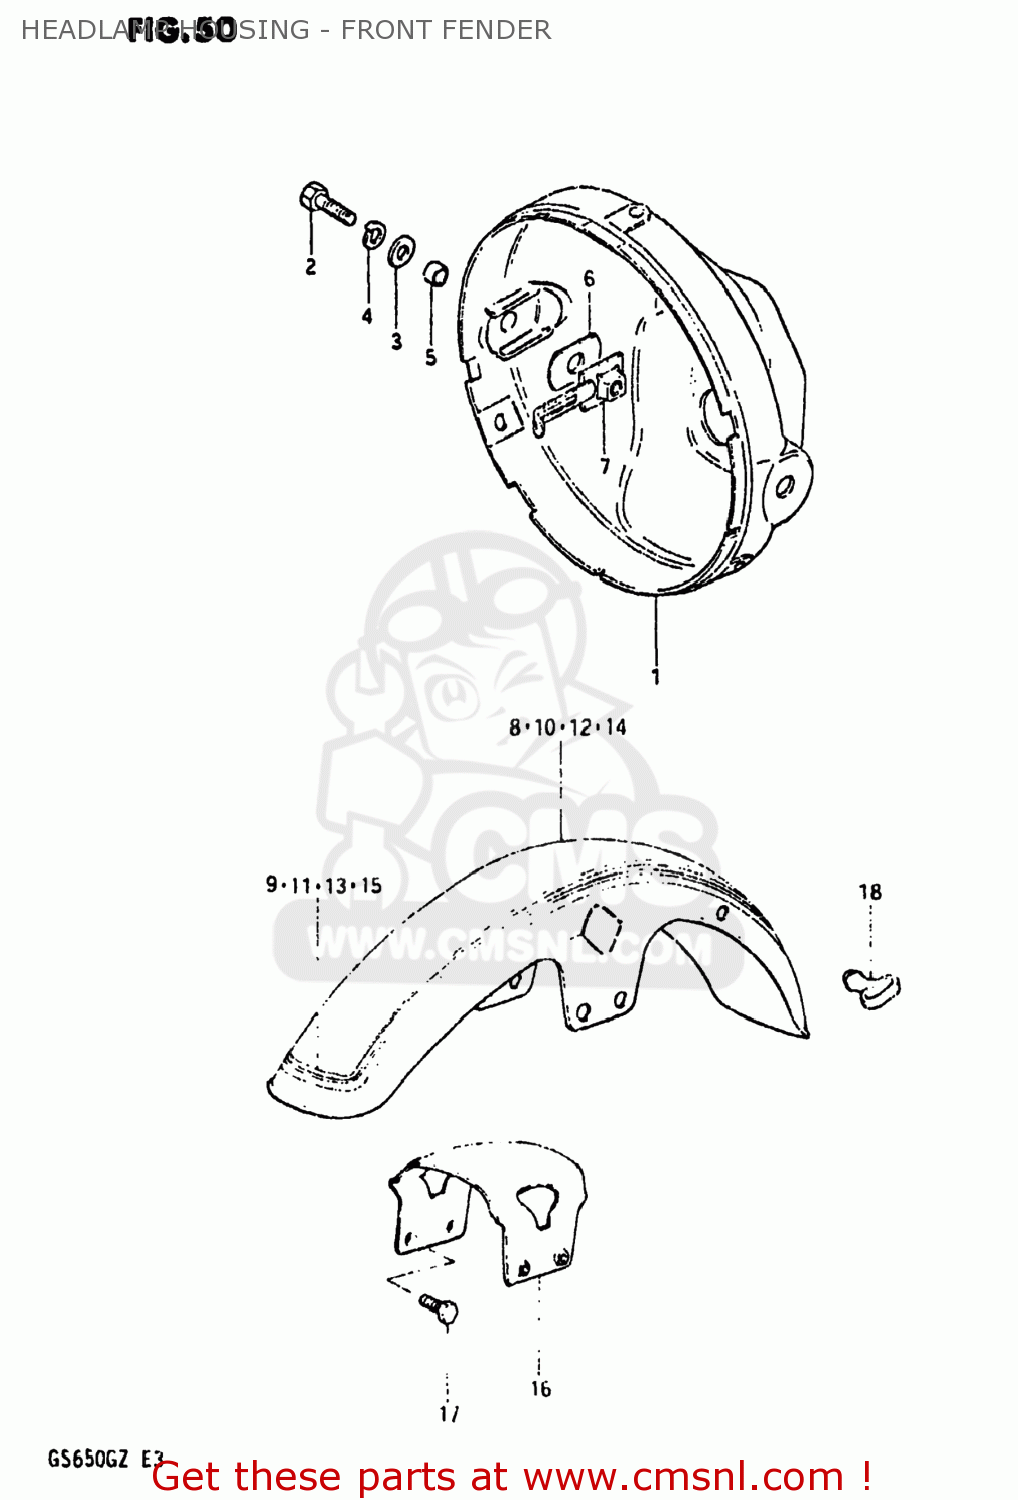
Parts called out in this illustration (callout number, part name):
1	HOUSING,HEADLAMP
2	BOLT
3	WASHER
4	LOCK WASHER
5	SPACER (8.8X12X7)
6	CUSHION
7	PLATE,HEADLAMP HOUSING
8	FENDER,FRONT
9	TAPE,FRONT FENDER
10	FENDER,FRONT
11	TAPE,FRONT FENDER
12	FENDER,FRONT
13	TAPE SET,FRONT FENDER
14	FENDER,FRONT
15	TAPE,FRONT FENDER
16	BRACE,FRONT FENDER
17	BOLT 8X16
18	GUIDE,CABLE
